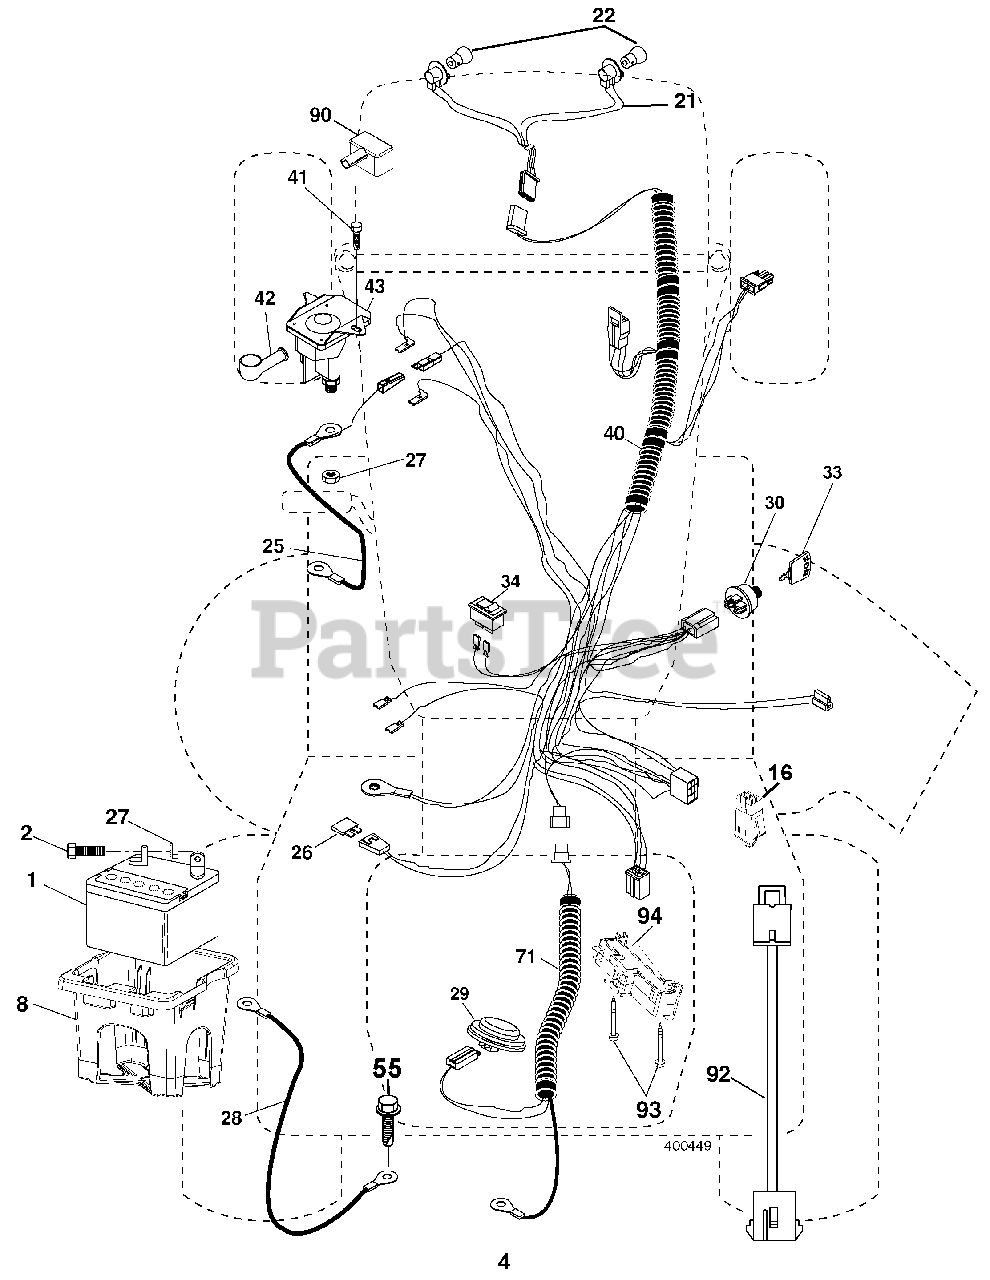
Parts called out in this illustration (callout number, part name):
1	Battery
2	Bolt Hex Hd 1/4-20 unc x 3/4
8	Box Battery
16	Switch Interlock
21	Harness Socket Light
22	Bulb, Light # 1156
25	Cable Battery 6 Ga. Red 14.5
26	Fuse
27	Nut Keps Hex 1/4-20 unc
28	Cable Ground 18" Rear Battery Blk 6 Ga.
29	Switch Seat
30	Switch Ign
33	Key Ign Molded Generic
34	Switch Light/Reset
40	Harness Ign
41	Screw 1/4-20 unc x 1/2
42	Cover Terminal Red
43	Solenoid
55	Screw 5/16-18 x 3/4
71	Harness Ign. Chass.
90	Cover Terminal
92	Harness Pigtail Reverse Switch
93	Screw Plastic 10-14 x 2.0
94	Modual Reverse ROS
